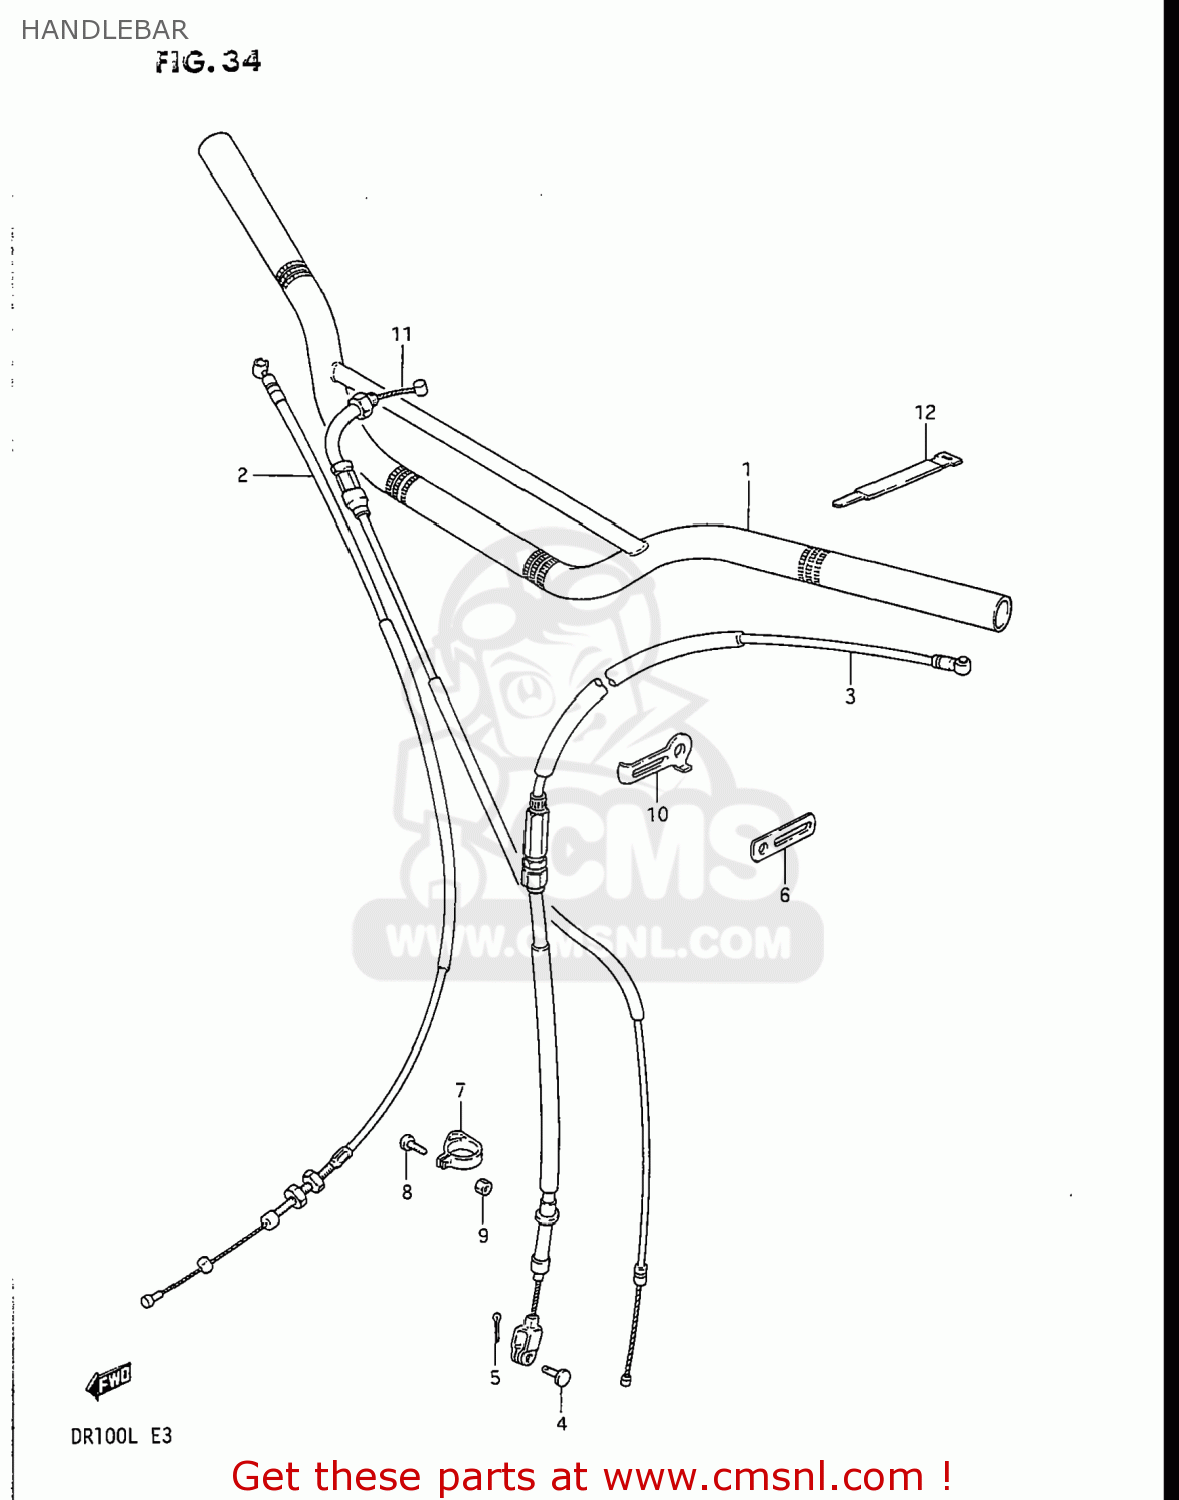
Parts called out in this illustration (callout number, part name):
1	HANDLEBAR
2	CABLE,FR BRAKE
3	CABLE ASSY,CLUTCH
4	PIN(L:15)
5	PIN
6	CLAMP
7	CLAMP,CABLE
8	SCREW
9	NUT 5MM
10	CLAMP,CABLE
11	CABLE ASSY,THROTTLE
12	CLAMP
